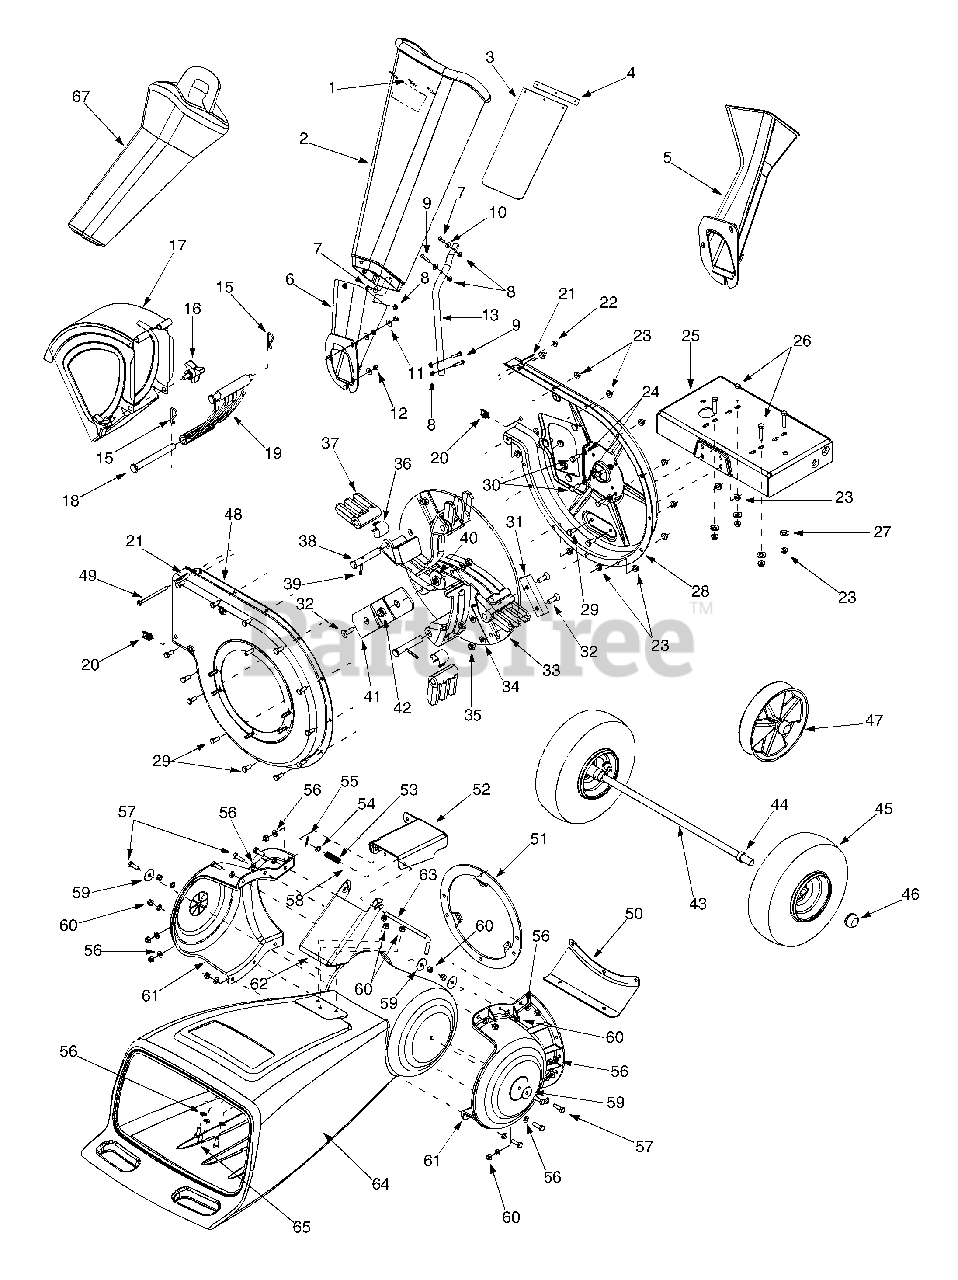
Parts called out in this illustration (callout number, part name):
1	Pop Rivet
2	Chipper Chute
3	Chute Flap
4	Chute Flap Strip
8	Hex Lock Nut 1/4-20
9	Hex Cap Screw 1/4-20 x 1.25
10	Flat Washer.28 ID x.74 OD
11	Bell Washer.340 ID x.872 OD
12	Hex Nut 5/16-18
15	Cotter Pin
16	Wing Knob 5/16-18
18	Clevis Pin
20	U-Nut 5/16-18
21	Spacer
22	Hex Lock Nut 1/4-20
23	Hex Lock Nut 5/16-18
24	Lock Washer 5/16
26	Hex Cap Screw 5/16-18 x 1.50
27	Bell Washer 5/16 x 1.0
29	Hex Cap Screw 5/16-18 x.75
30	Hex Cap Screw 5/16-24 x.75
31	Chipper Blade
32	Hex Cap Screw 5/16-24 x 1.0
33	Impeller Assembly
34	Lock Washer 5/16
35	Hex Lock Nut 5/16-24
36	Pin Clip
37	Flail Blade
38	Clevis Pin
40	Flat Washer 3/8 x 1.25
41	Shredder Blade
42	Hex Cap Screw 3/8-24 x 2.25
43	Axle Assembly
43	Axle Assembly Model 462, 463
44	Spacer
46	Push Cap
47	Wheel Complete 10 x 4 x 4
47	Wheel Assembly 10.0 x 2.5 Model 462, 463
49	Hex Cap Screw 1/4-20 x 3.75
53	Compression Spring 1.75
54	Flat Washer
55	Cotter Pin
56	Flat Washer.330 ID x.630 OD
57	Hex Cap Screw 5/16-18 x 1.0
59	Flat Washer.320 ID x 1.25 OD
60	Hex Lock Nut 5/16-18
61	Hopper Collar
63	Lock Rod
64	Hopper Assembly
65	Hex Cap Screw 5/16-18 x.75
67	Tamper Plug (If Equipped)
